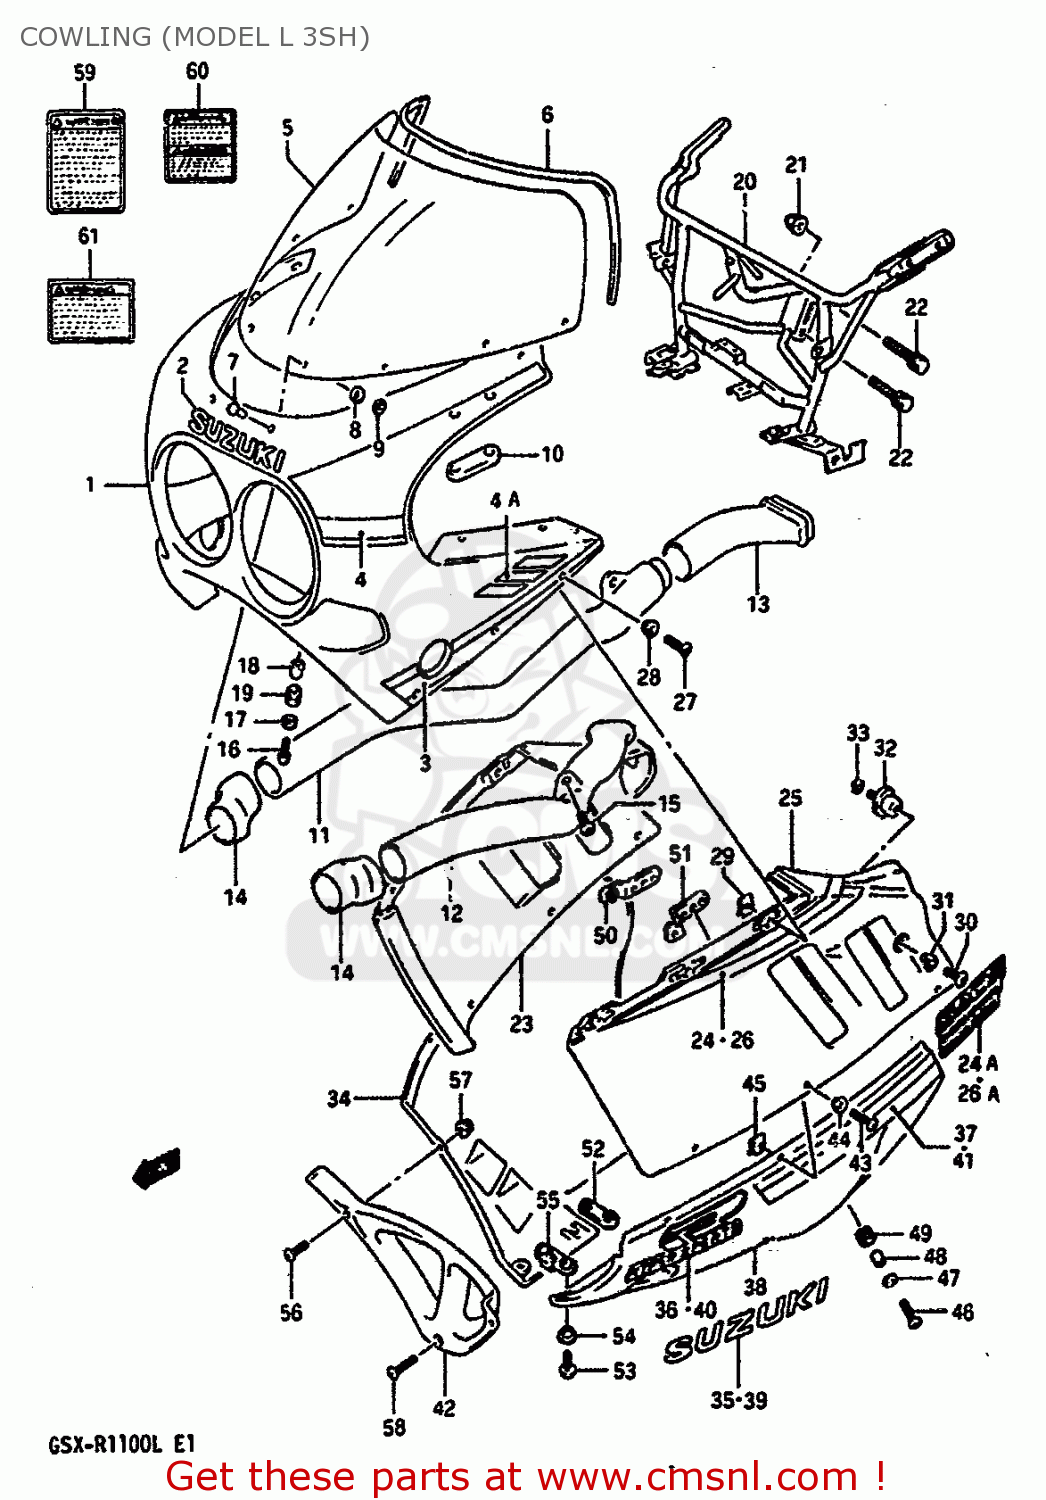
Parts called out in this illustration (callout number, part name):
1	BODY ASSY,COWLING
2	EMBLEM,COWLING UPR
3	TAPE SET,COWLING,UPPER SIDE
4	TAPE SET,COWLING,UPPER,FRONT
4A	TAPE SET,COWL
5	SCREEN,WIND
6	MOLDING
7	PIN,WINDSCREEN
8	CUSHION
9	NUT
10	CUSHION,RR VIEW MIRRORR
11	PIPE,AIR INTAKE FR,R
12	PIPE,AIR INTAKE,FRONT
13	PIPE,AIR INTAKE RR,R
14	JOINT,AIR INTAKE
15	SCREW, CENTER
16	SCREW(6X20)
17	WASHER(6.5X18X1)
18	SPACER
19	CUSHION
20	BRACE,COWLING
21	NUT ,8MM
22	BOLT
23	COVER,SIDE RH (BLUE/WHITE)
24	TAPE,COWL SIDE,R
24A	EMBLEM,"SACS"
25	COVER,COWLING,
26	TAPE,COWL SIDE,L
26A	EMBLEM,"SACS"
27	SCREW(5X18)
28	WASHER(5.2X14X1.5)
29	NUT,HEADLAMP HOUSING,UPPER
30	SCREW(6X12)
31	WASHER(6.3X16X1.5)
32	CUSHION,COWLING
33	WASHER,LOCK
34	COWLING COMP,UNDER,RIGHT
35	EMBLEM
36	EMBLEM,COWLING,UNDER
37	TAPE,COWLING,UNDER STRIPE
38	COWLING,UNDER,LEFT
39	EMBLEM,COWLING UNDER,L
40	EMBLEM,COWLING,UNDER
41	TAPE,COWLING,UNDER STRIPE
42	COWLING,UNDER,CENTER
43	SCREW(5X18)
44	WASHER(5.2X14X1.5)
45	NUT,HEADLAMP HOUSING,UPPER
46	SCREW(6X20)
47	WASHER(6.5X18X1)
48	SPACER
49	CUSHION
50	BRACKET
51	BRACE,COWLING UNDER,LH
52	BRACE,COWLING LWR COVER RR
53	SCREW(6X16)
54	WASHER(6.3X16X1.5)
55	BRACE,COWLING LWR COVER
56	SCREW(5X14)
57	NUT
58	SCREW(6X16)
59	LABEL (WARNING SCREEN)
60	LABEL (WARNING)
61	LABEL, WARNING SAFETY
